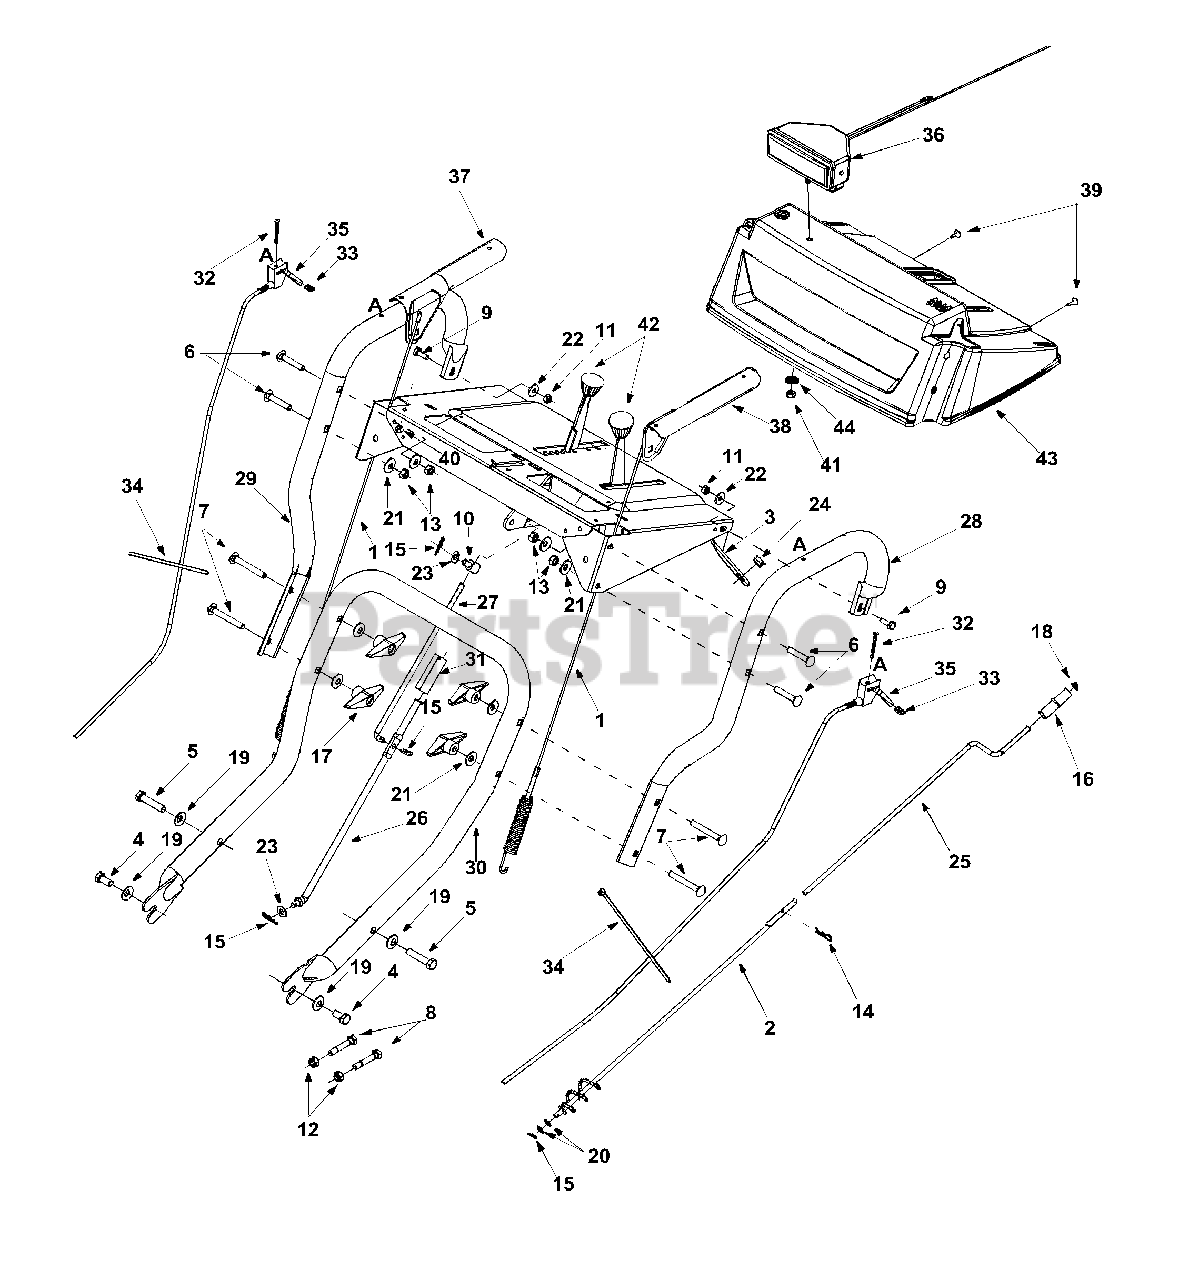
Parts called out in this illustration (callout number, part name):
1	Cable Assembly: Auger/Drive
4	Hex Screw 3/8-16 x .75"
5	Hex Screw 3/8-16 x 1.75"
6	Carriage Bolt 5/16-18 x 1.75"
7	Carriage Bolt 5/16-18 x 2.5"
8	Shear Bolt 5/16-18 x 1.75"
9	Hex Screw 1/4-20 x .75"
10	Ferrule
11	Hex Nut 1/4-20
12	Hex Lock Nut
13	Hex Nut
14	Hairpin Clip
15	Hairpin Clip
16	Chute Crank Knob
18	Push Cap
19	Bell Washer
20	Flat Washer
21	Beleville Washer
22	Bell Washer
23	Flat Washer
24	Plastic Bushing
26	Lower Shift Rod
27	Upper Shift Rod
31	Clutch Rod Connector
32	Oval C-Sunk Screw
33	Flat Weld Nut
34	Cable Tie
35	Trigger Control
36	Light Assembly
37	Handle Engagement RH
38	Handle Engagement LH
39	Special B Screw
40	Hex Sems Nut
41	Hex Lock Nut
42	Shift Knob
43	Handle Panel
44	5/16 Washer
